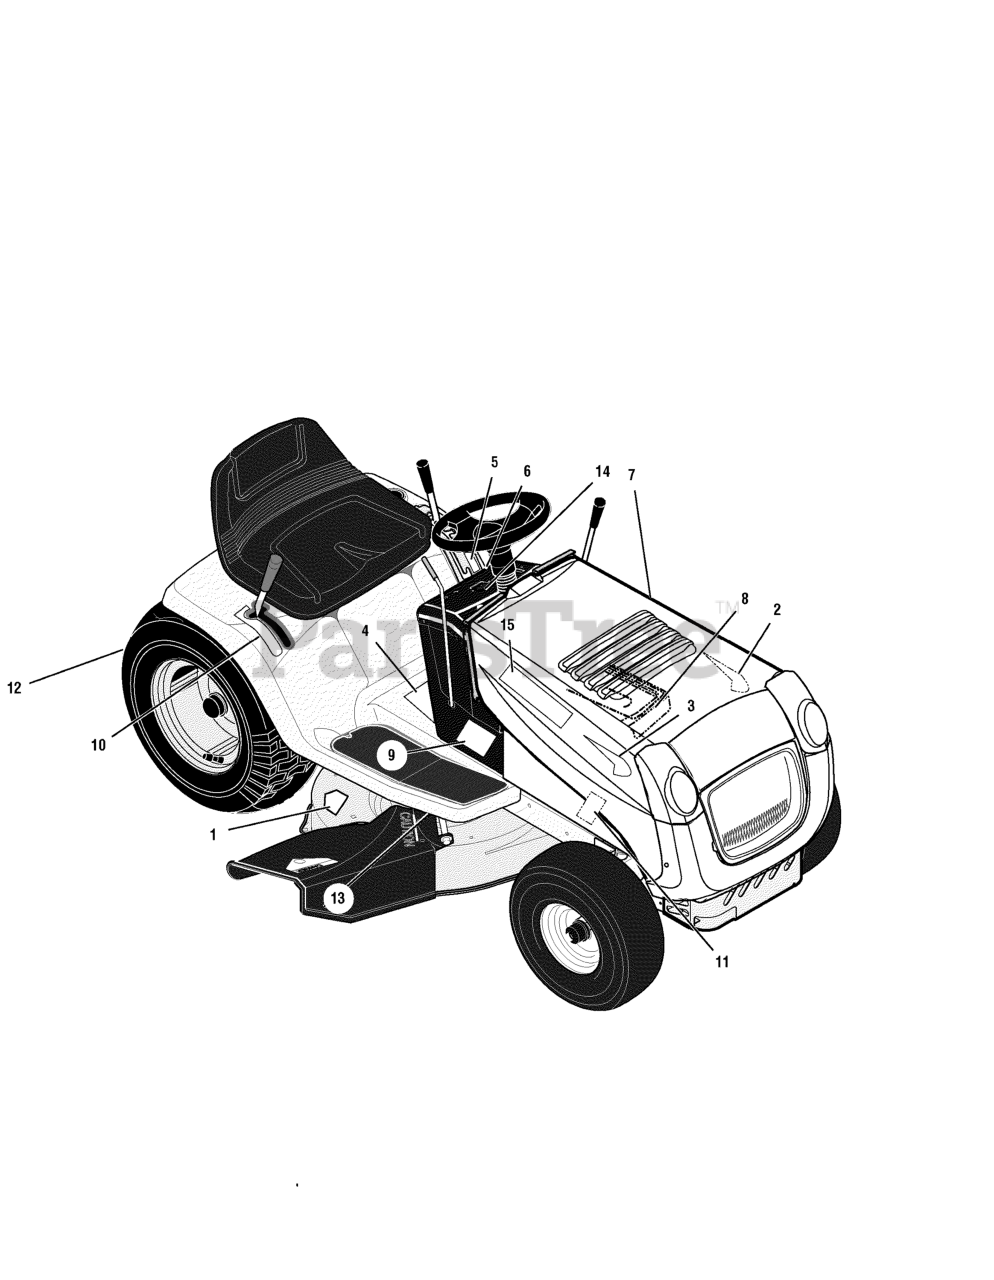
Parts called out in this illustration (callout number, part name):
1	DECAL, CUT FINGER SYMBOLS
2	DECAL, 125/76 LH
3	DECAL, 125/76 RH
4	DECAL, WARNING EXPORT
5	DECAL, 7 POS CUT HGT SM SD
6	DECAL, DECK LEVEL
7	DECAL, NO STEP EXPORT
8	DECAL, BRAKE/CLUTCH EXP
9	DECAL, B&S LOGO IC
10	DECAL, 5 SPEED
11	DECAL, HEAT SHIELD WARNING
12	DECAL, DRAWBAR WARNING PICT
13	DECAL, WARNING-PINCH POINT
14	DECAL, DASH/SYMBOLS W1
15	DECAL, SENTINEL R & L
